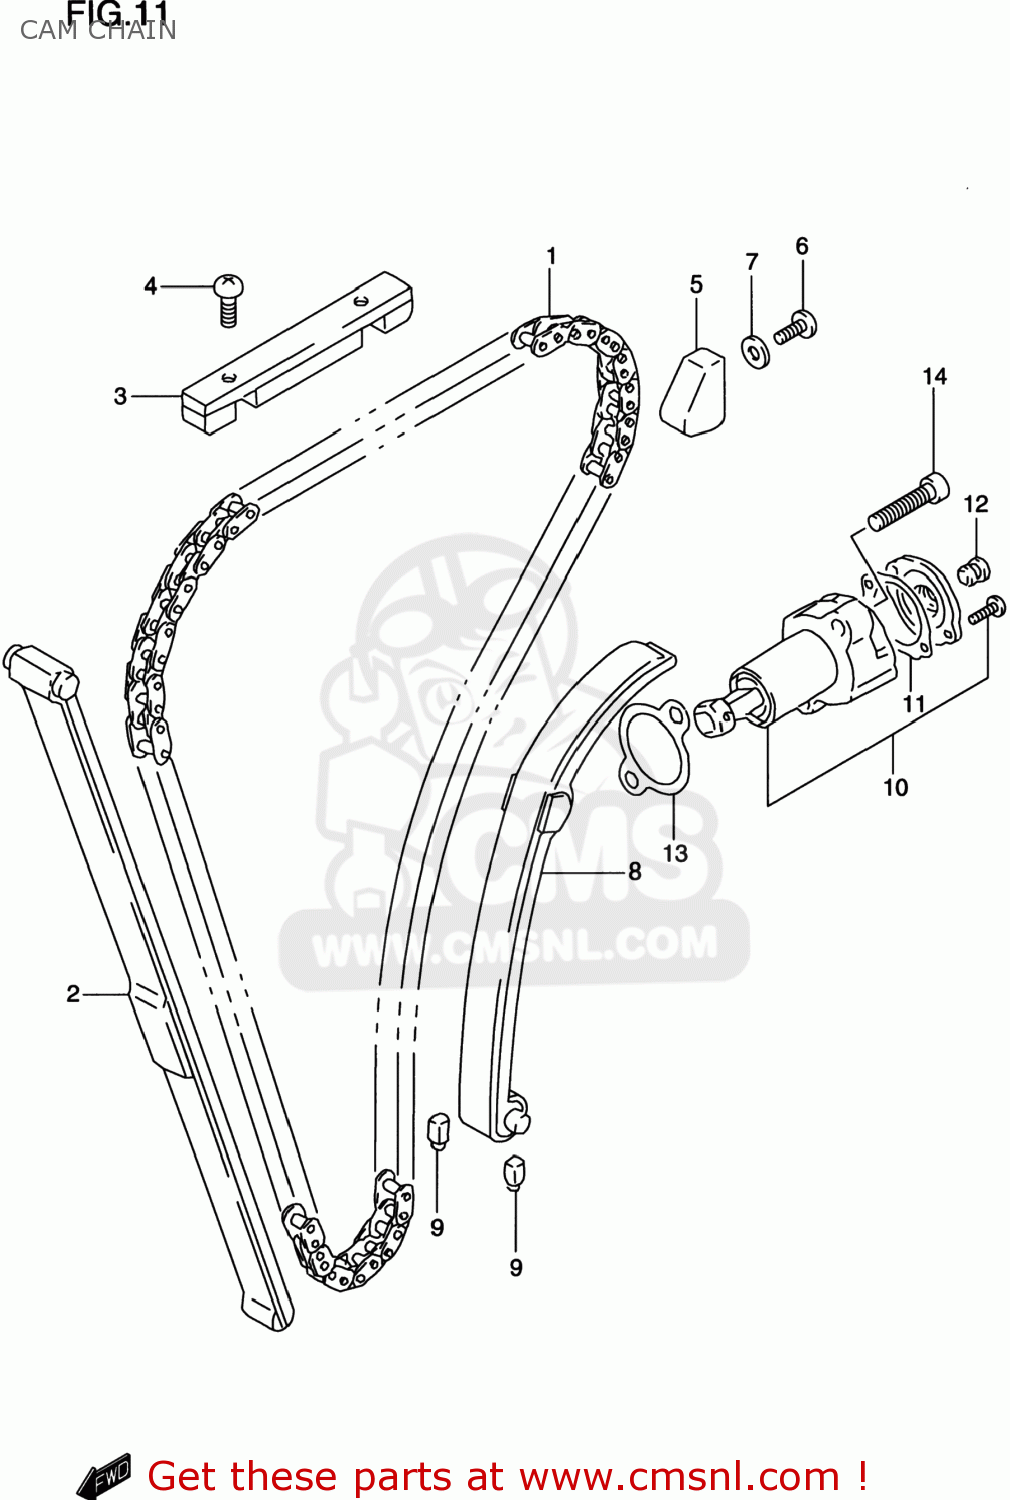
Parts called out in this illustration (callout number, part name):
1	CHAIN,CAMSHAFT DRIVE(120L)
2	GUIDE,CAM CHAIN NO.1
3	GUIDE,CAM CHAIN
4	SCREW
5	GUIDE,CAM CHAIN
6	BOLT
7	GASKET(5.8X13X1.2) (NAS)
8	TENSIONER,CAM CHAIN
9	CUSHION,CAM CHAIN TENSIONER
10	ADJUSTER ASSY,TENSIONER
11	GASKET,ADJUSTER CAP (NAS)
12	PLUG,ADJUSTER
13	GASKET,TENSIONER ADJUSTER (NAS)
14	BOLT,CL.COVER
